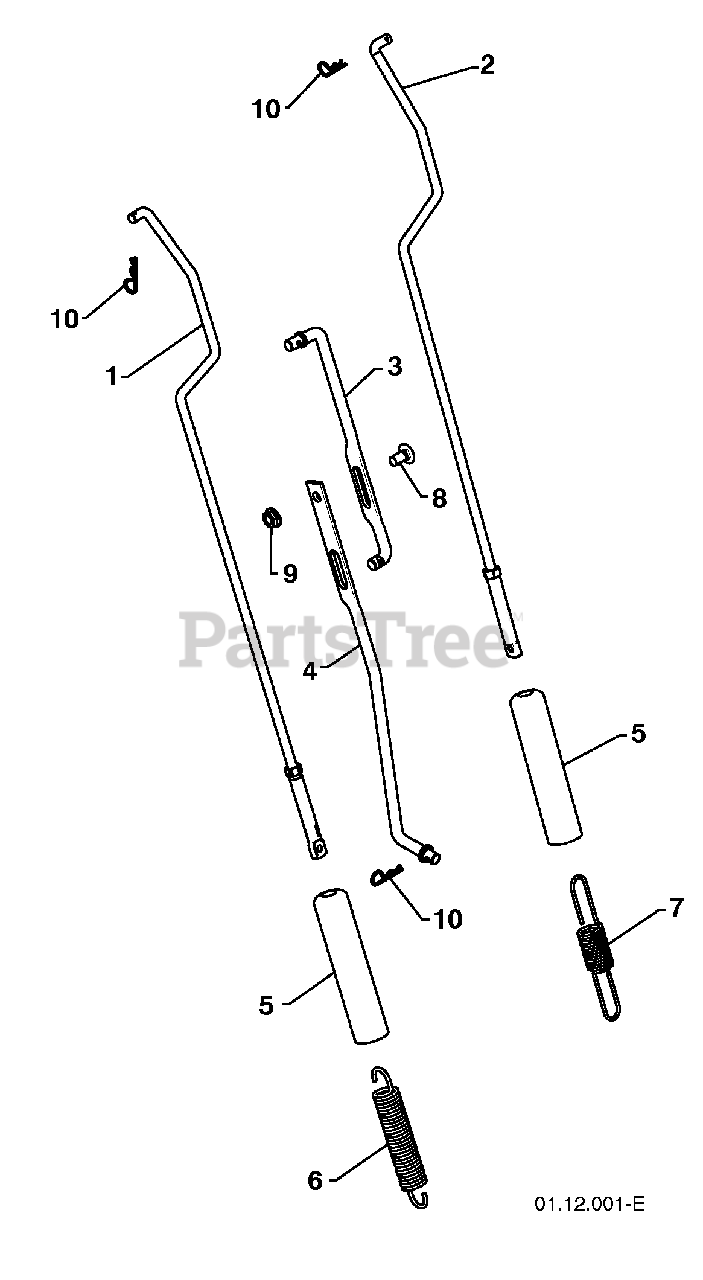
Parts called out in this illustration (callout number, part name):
1	IMPELLER ROD ASSEMBLY
2	TRACTION ROD ASSEMBLY
3	SHIFTER ROD TOP
4	SHIFTER ROD BOTTOM
5	SPRING SLEEVE
6	IMPELLER SPRING
7	TRACTION SPRING
8	CARRIAGE BOLT 5/16-18 X .625
9	NUT 5/16-18
